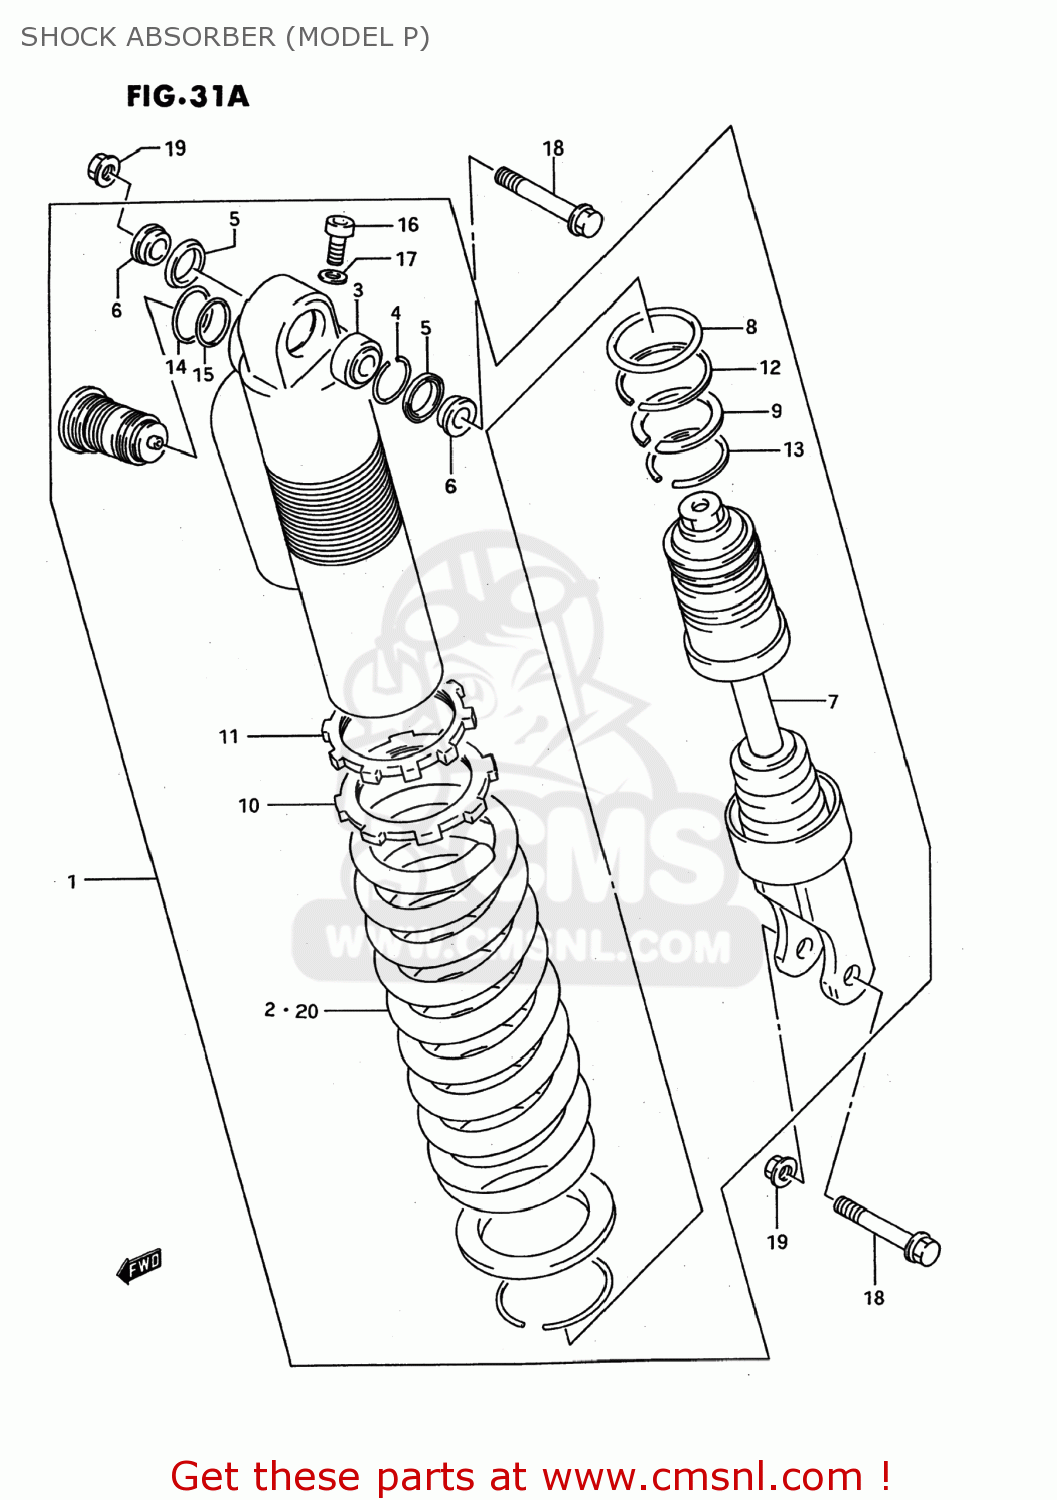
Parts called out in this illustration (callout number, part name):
1	ABSORBER ASSEMBLY,REAR SHOCK
2	SPRING
3	BEARING,RR CUSHION LEVER RR
4	RING,STOPPER
5	SEAL,DUST
6	COLLAR
7	ROD,PISTON
8	O RING
9	STOPPER
10	GUIDE,SPRING
11	NUT
12	RING,STOPPER
13	RING,STOPPER
14	O RING
15	O RING,CTR BOLT UPR
16	BOLT,REAR SHOCK ABSORBER
17	GASKET,DRAIN,PLUG (NAS)
18	BOLT,REAR SHOCK ABSORBER
19	NUT
20	SPRING
